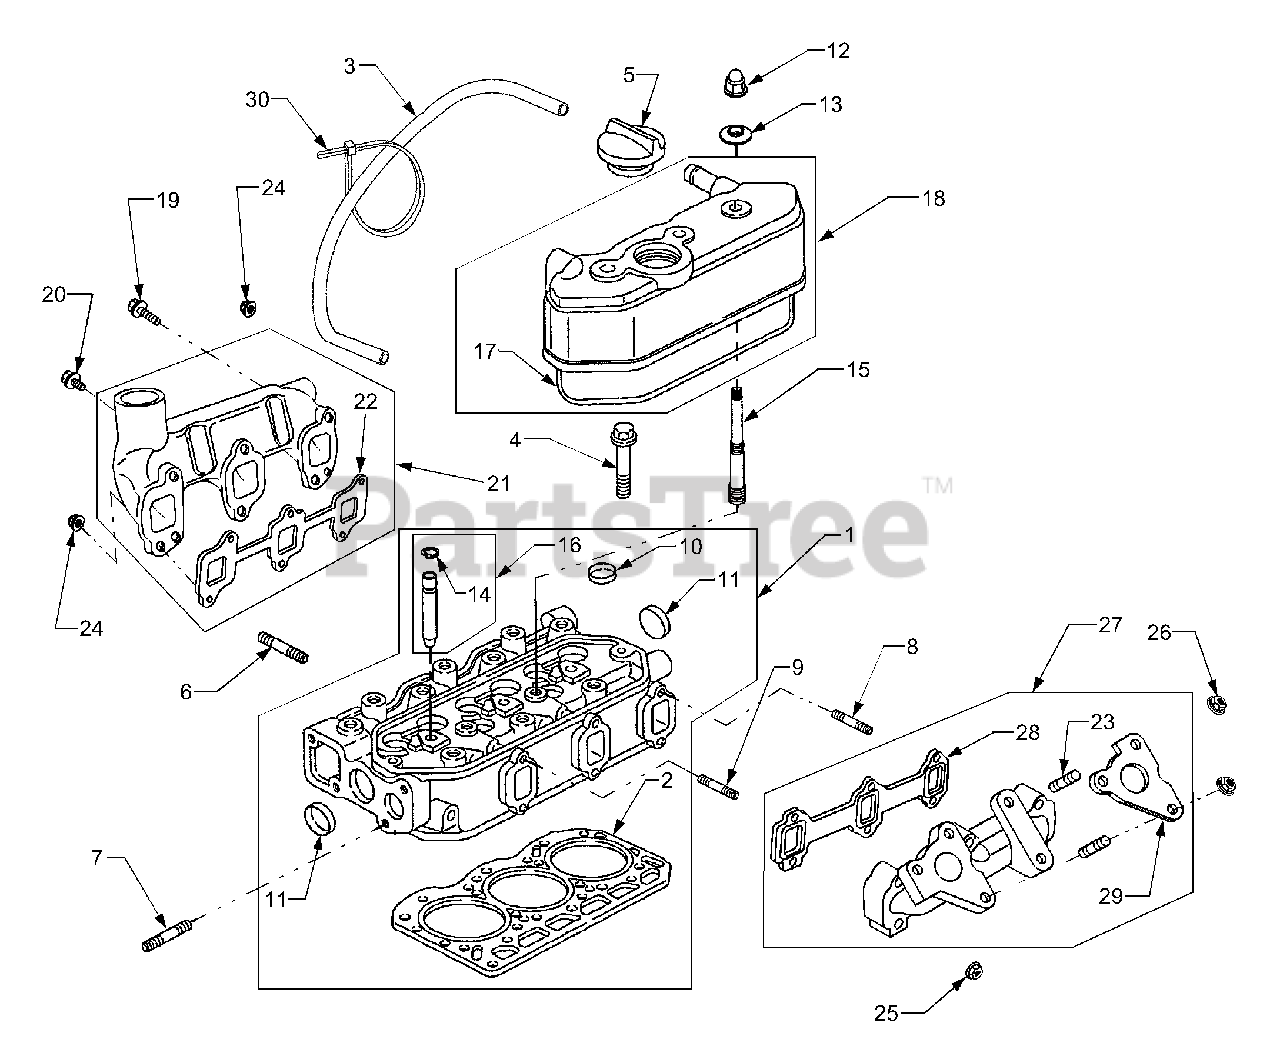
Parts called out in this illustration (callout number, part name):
1	Head, Cylinder
2	Gasket, Cylinder Head
3	Tube, Breather
4	Screw, Metric
5	Cap, Oil Fill
6	Stud, Metric
7	Stud, Metric
8	Stud, Metric
9	Stud, Metric
10	Plug, Welch
11	Plug, Welch
12	Nut, Hex Metric
13	Washer, Sealing
14	Ring, Retainer
15	Stud, Rocker Arm
16	Bushing, Guide
17	Gasket, Rocker Cover
18	Cover, Rocker
19	Screw, Hex, 6mm
20	Screw, Hex, 6mm
21	Manifold, Intake
22	Gasket, Intake Manifold
23	Stud, Exhaust Manifold
24	Nut, Hex Metric
25	Nut, Hex Metric
26	Nut, Hex Metric
27	Manifold, Exhaust
28	Gasket, Exhaust Manifold
29	Gasket, Muffler
30	Tie, Cable
